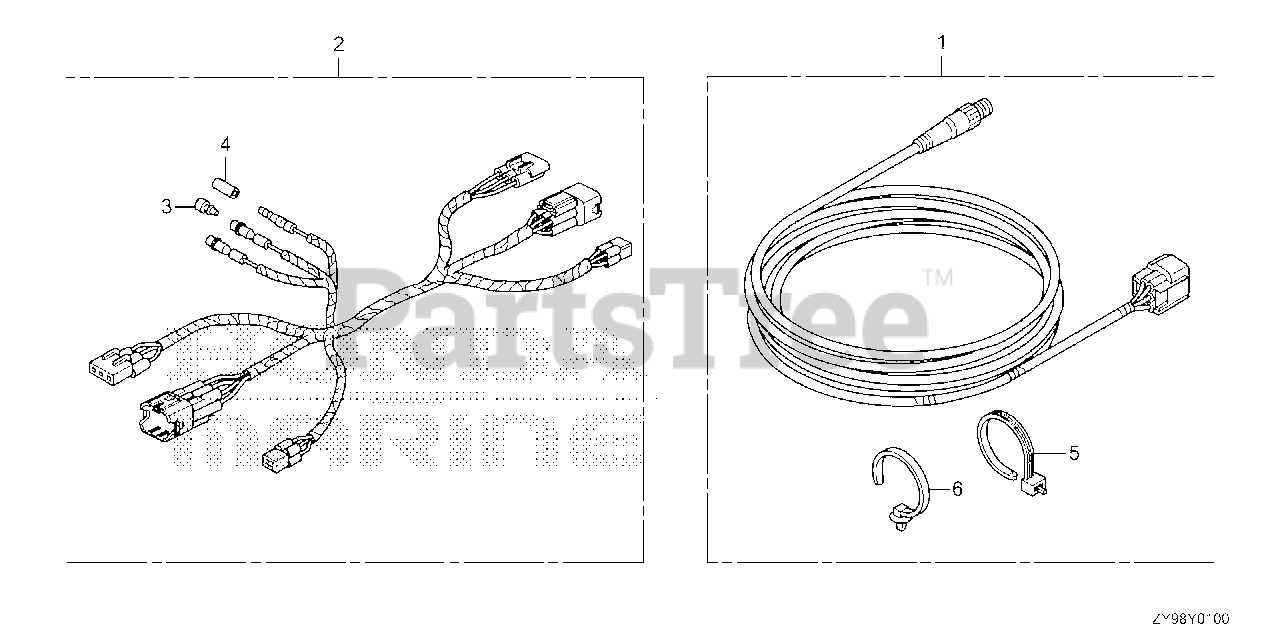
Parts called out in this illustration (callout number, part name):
1	KIT, CABLE (6FT) (NMEA)
2	HARNESS ASSY., REMOTE CONTROL SUB
3	PLUG, CONNECTOR (INNER)
4	PLUG, CONNECTOR (OUTER)
5	TIE, CABLE
6	CLIP, HARNESS BAND (155.3MM) (BLACK)
